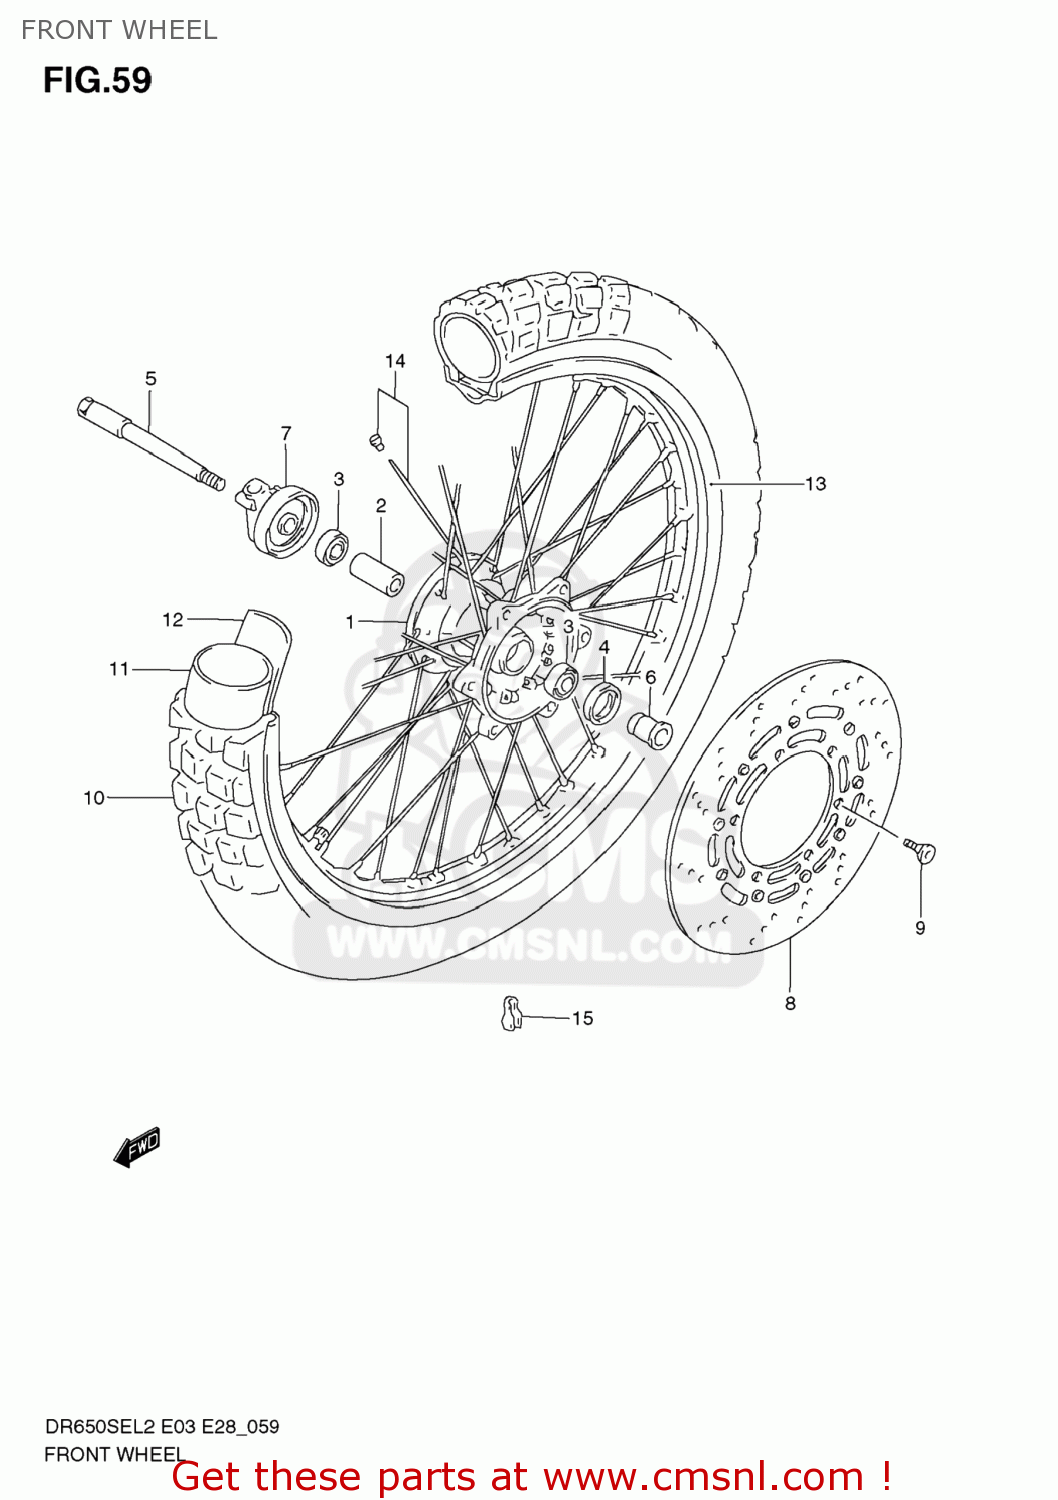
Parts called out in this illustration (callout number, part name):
1	HUB,FR WHEEL
2	SPACER,FR HUB BEARING
3	BEARING
4	SEAL,OIL(23X35X6)
5	AXLE,FR
6	SPACER,FR AXLE,L
7	BOX ASSY,SPEEDOMETER GEAR
8	DISC,FR BRAKE
9	BOLT(8X20)
10	TIRE,FR(90/90-21 54S)
11	TUBE ASSY,WHEEL INNER
12	PROTECTOR,WHL INR TUBE
13	RIM,FR WHEEL(21X1.85)
14	SPOKE SET,FR WHEEL
15	BALANCER,WHEEL(20G)
